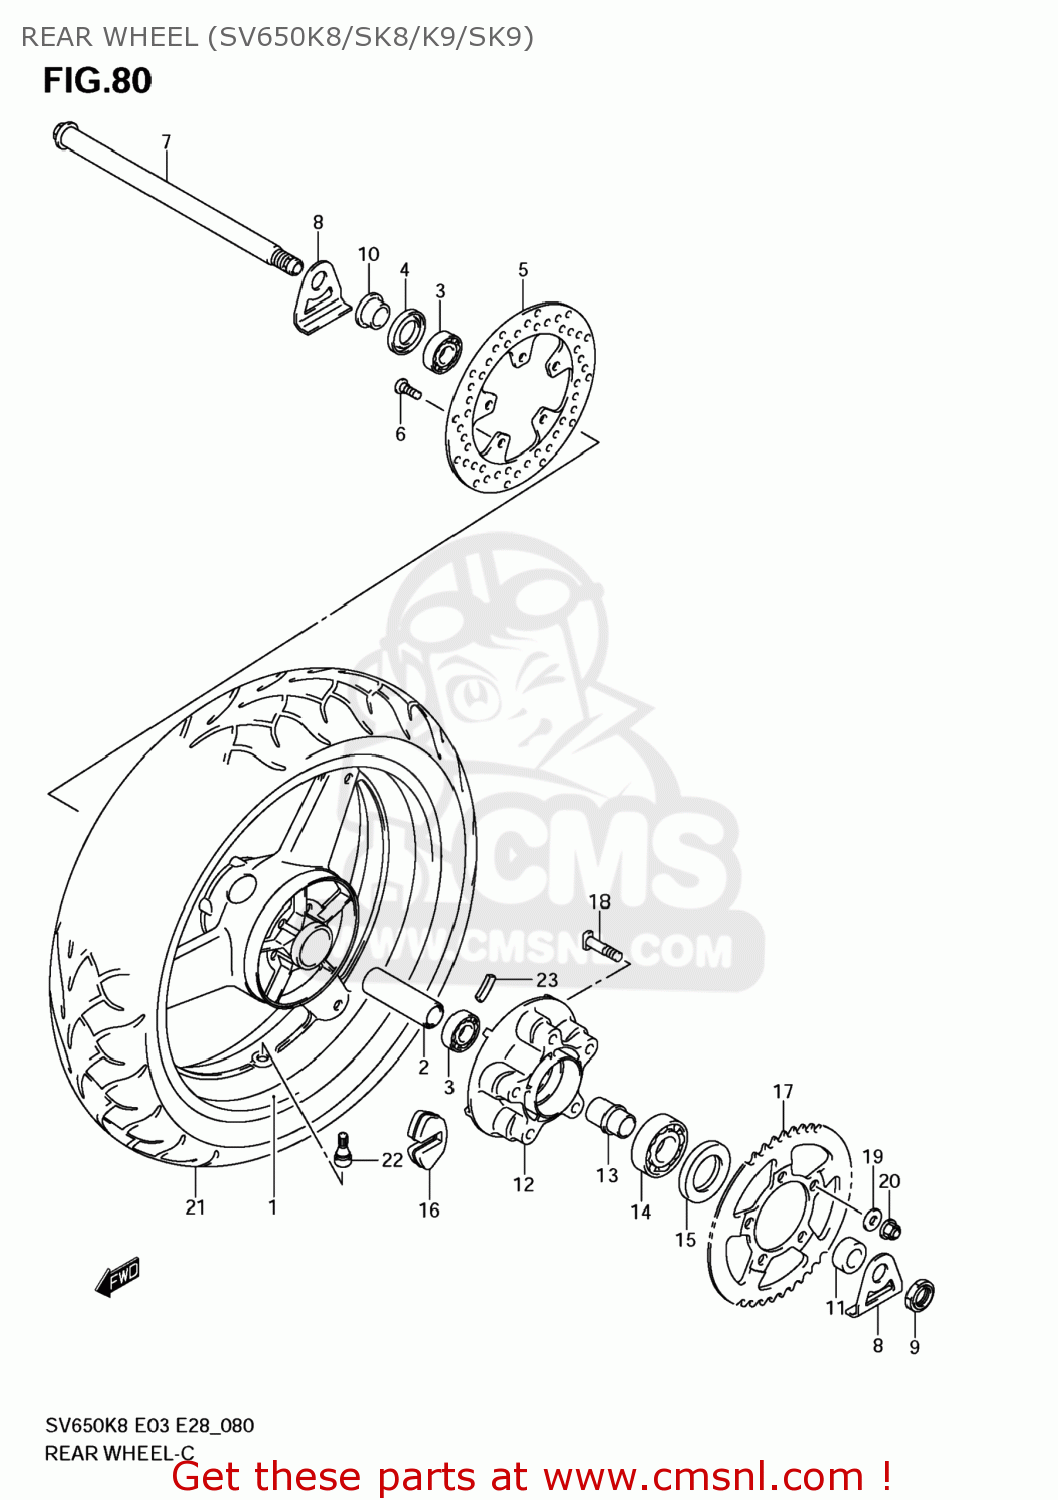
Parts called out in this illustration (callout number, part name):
1	WHEEL,RR(17M/CXMT4.50)
2	SPACER(20.5X28X88)
3	BEARING(20X47X14)
4	SEAL,OIL(28X47X7)
5	DISC,RR BRAKE
6	BOLT(8X33)
7	AXLE,RR
8	WASHER,CHAIN ADJUSTER
9	NUT
10	SPACER,RR AXLE,R
11	SPACER,RR AXLE,L
12	DRUM,RR SPROCKET MOUNTING
13	RETAINER,RR HUB BEARING
14	BEARING(25X62X17)
15	SEAL,OIL(35X62X8)
16	ABSORBER,RR HUB SHOCK
17	SPROCKET,RR(NT:45-525)
18	BOLT(10X47)
19	WASHER(10.5X22X2.3)
20	NUT
21	TIRE,RR(160/60 ZR17M/C 69W)
22	VALVE ASSY,WHEEL RIM(TR412)
23	BALANCER,WHEEL(10G)
